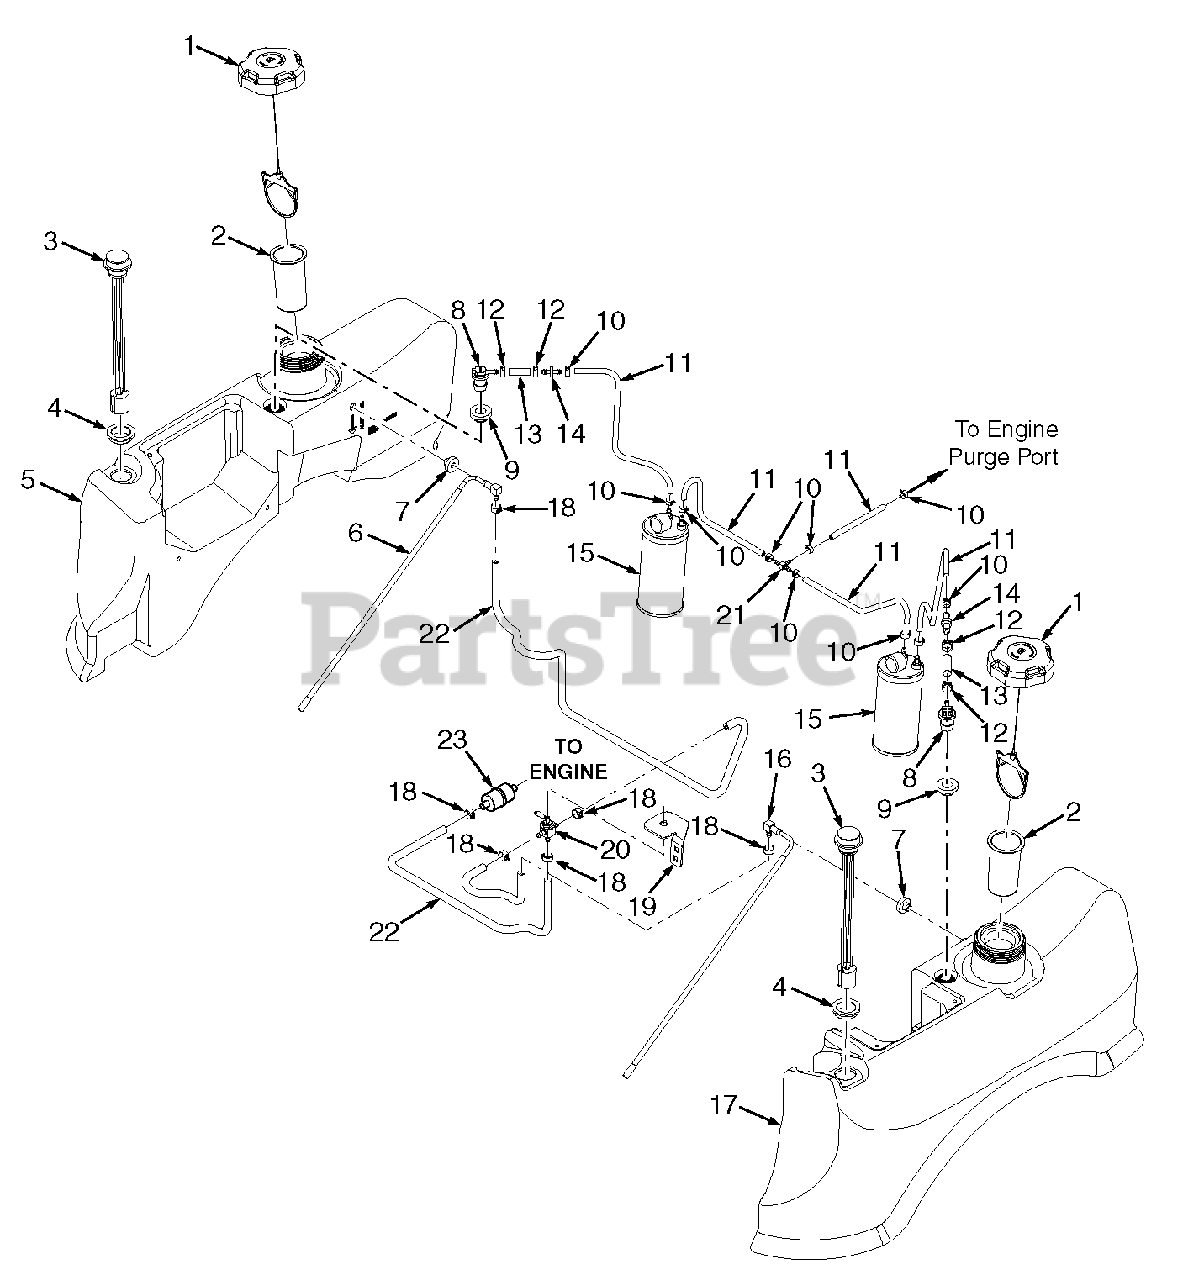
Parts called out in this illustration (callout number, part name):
1	Fuel Cap, Tethered
1	Fuel Cap, Tethered (California Only)
2	Tube, Fuel Tank Insert - 4"
3	Fuel Gauge Assembly
4	Seal, Fuel Gauge
5	Fuel Tank Assembly, RH
6	Fuel Tube Assembly
7	Bushing, .56 Viton
8	Remote Vent
9	Grommet, Viton
10	Clamp, Vapor Recovery Hose
11	Hose, 3/16" (order by inch)
12	Clamp, Fuel Hose 7/32
13	Hose, Vapor Recovery (order by inch)
14	Mender, 1/4 x 3/16
15	Carbon Canister, 400cc
15	Dust Filter, Carbon Canister
16	Fuel Tube Assembly, LH
17	Fuel Tank Assembly, LH
18	Clamp, Fuel Hose 1/4" I.D.
19	Mounting Bracket, Fuel Valve
20	Valve, Fuel Shut Off
21	Tee, 3/16 x 3/16 x 3/16 Union, Hose Barb
22	Hose, Non-Perm Fuel 1/4" I.D.
23	Fuel Filter
